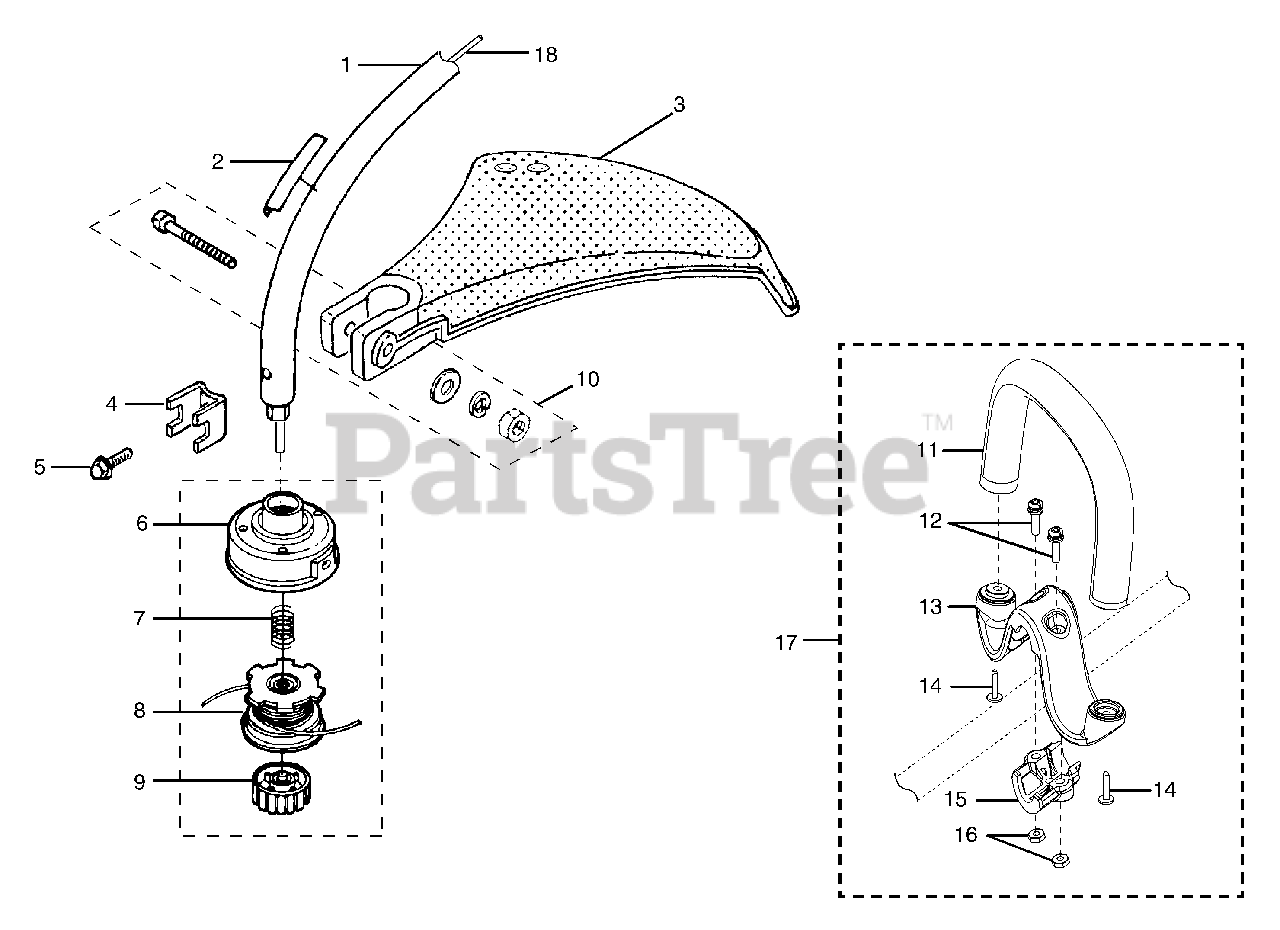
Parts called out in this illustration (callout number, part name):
1	BOOM ASSEMBLY KIT
2	BOOM DECAL (WARNING)
3	GRASS DEFLECTOR
4	CLAMP
5	SCREW
6	HOUSING AND EYELETS
7	COMPRESSION SPRING
8	SPOOL W/LINE (.095 in)
9	SPOOL RETAINER (RH/THREAD)
10	FASTENER PARTS KIT
11	ASSIST HANDLE W/GRIP
12	SCREW (12-24 x 1 SEMS)
13	M CLAMP
16	HEX NUT (12-24)
17	ASSIST HANDLE ASSEMBLY
18	FLEXIBLE SHAFT
